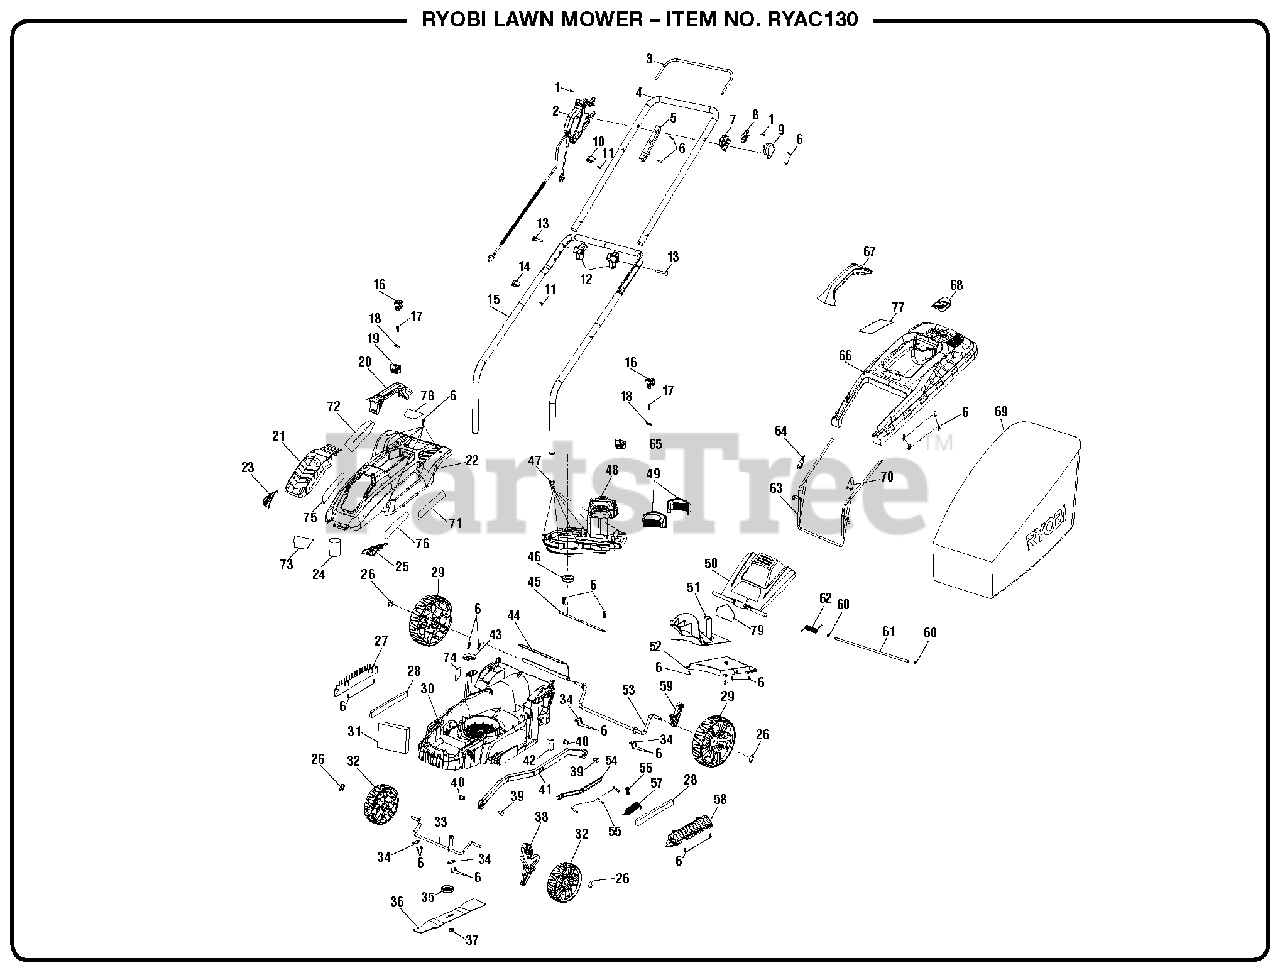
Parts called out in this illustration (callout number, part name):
1	Screw (M4 x 8 mm)
2	Control Box Assembly
3	Power Lever
4	Upper Handle Assembly
5	Lower Cover (Control Assembly)
6	Screw (M4.2 x 15 mm)
7	Bale Handle Cover (Right)
8	Bale Handle Holder
9	Bale Handle Cover (Left)
11	Screw w/Washer (M3 x 16 mm)
13	Bolt (M6 x 50 mm)
15	Lower Handle
16	Handle Height Adjustment Button
17	Torsion Spring (Height Adjustment)
19	Button Support
21	Motor Cover
23	Grass Protector (Right)
24	Counter Weight
25	Grass Protector (Left)
27	Air Inlet (Right)
32	Front Wheel
33	Front Wheel Axle
34	Axle Pressure Plate
35	Blade Holder
37	Hex Nut (M10, Flange)
38	Height Adjustment Lever Assembly
40	Lock Pin Seat
41	Front Lift Rod
45	Rear Skirt Plate
46	Bearing 6902Z
47	Screw (M4.2 x 18 mm)
49	Dust Proof Motor Cover
50	Rear Discharge Door
51	Mulching Plug
53	Rear Wheel Axle
54	Rear Lift Rod
55	Screw (M4.2 x 12 mm)
56	Screw w/Washer (M4.8 x 18 mm)
57	Retention Spring
58	Air Inlet (Left)
59	Axle Bracket
61	Rear Door Axle
62	Torsion Spring (Rear Door)
64	Bag Cover Plug (Right)
65	Button Support
68	Bag Indicator
70	Bag Cover Plug (Left)
71	Side Warning Label
72	Waring Icon Label
73	Front Logo Label
74	Height Adjustment Label
75	Feature Label
76	Feature Label
77	Bagger Warning Label
78	Data Label
79	Danger Label
